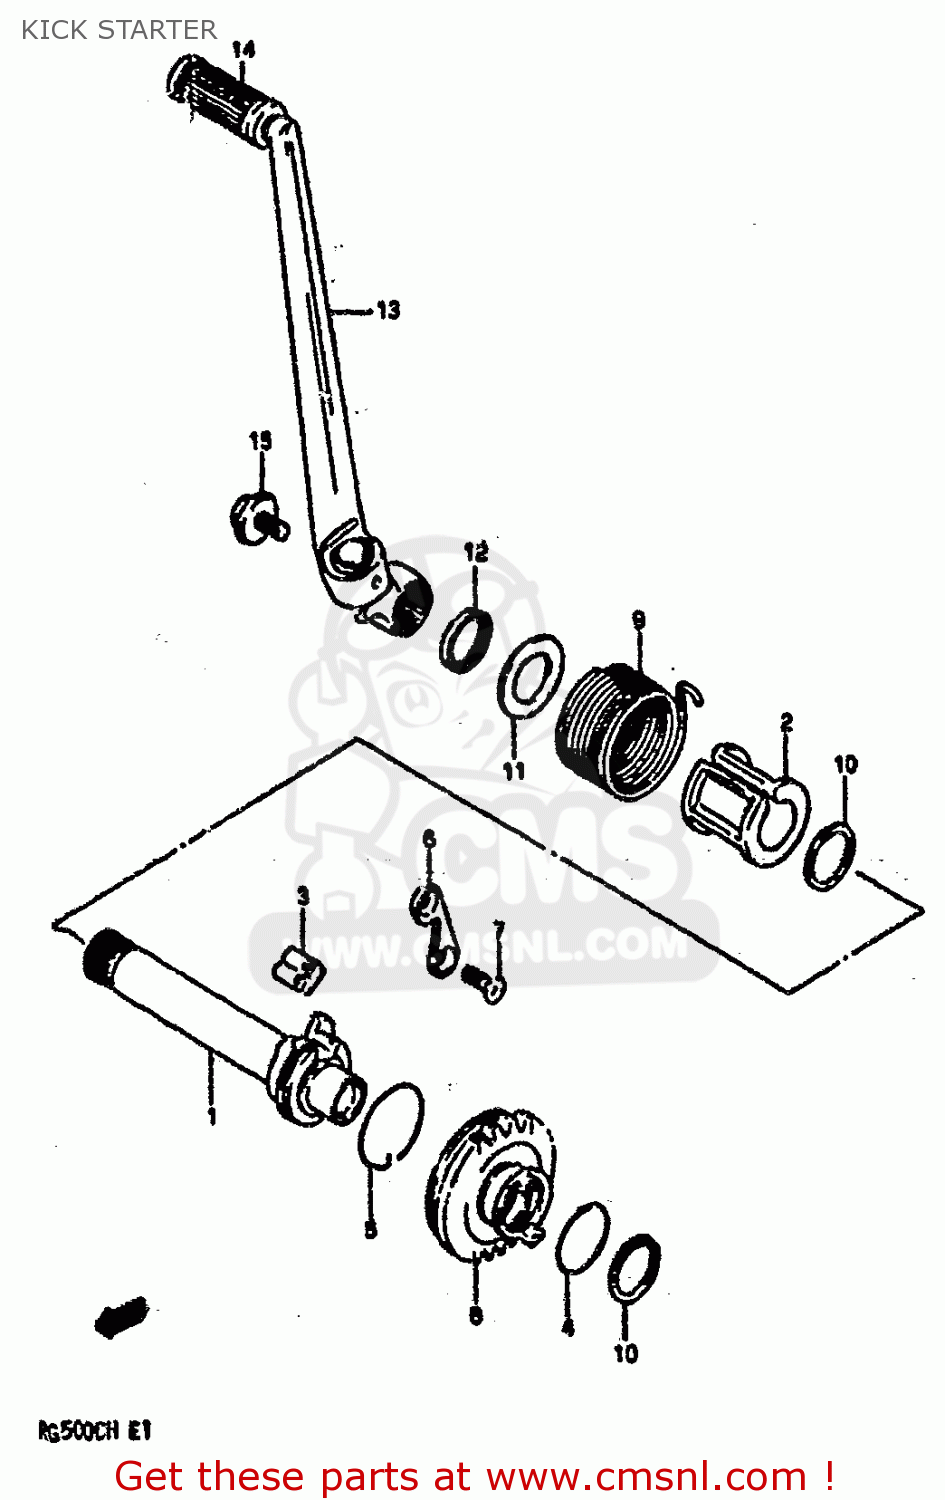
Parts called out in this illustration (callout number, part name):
1	SHAFT,KICK STARTER
2	GUIDE,SPRING
3	PAWL,KICK STARTER
4	CLIP
5	SPRING
6	STOPPER,KICK STARTER
7	SCREW
8	GEAR,KICK STARTER DRIVE (NT:21)
9	SPRING
10	WASHER,THRUST
11	WASHER
12	SEAL,OIL(20X27X5)
13	LEVER ASSY,KICK STARTER
14	RUBBER,KICK STARTER PEDAL
15	BOLT(8X14)
